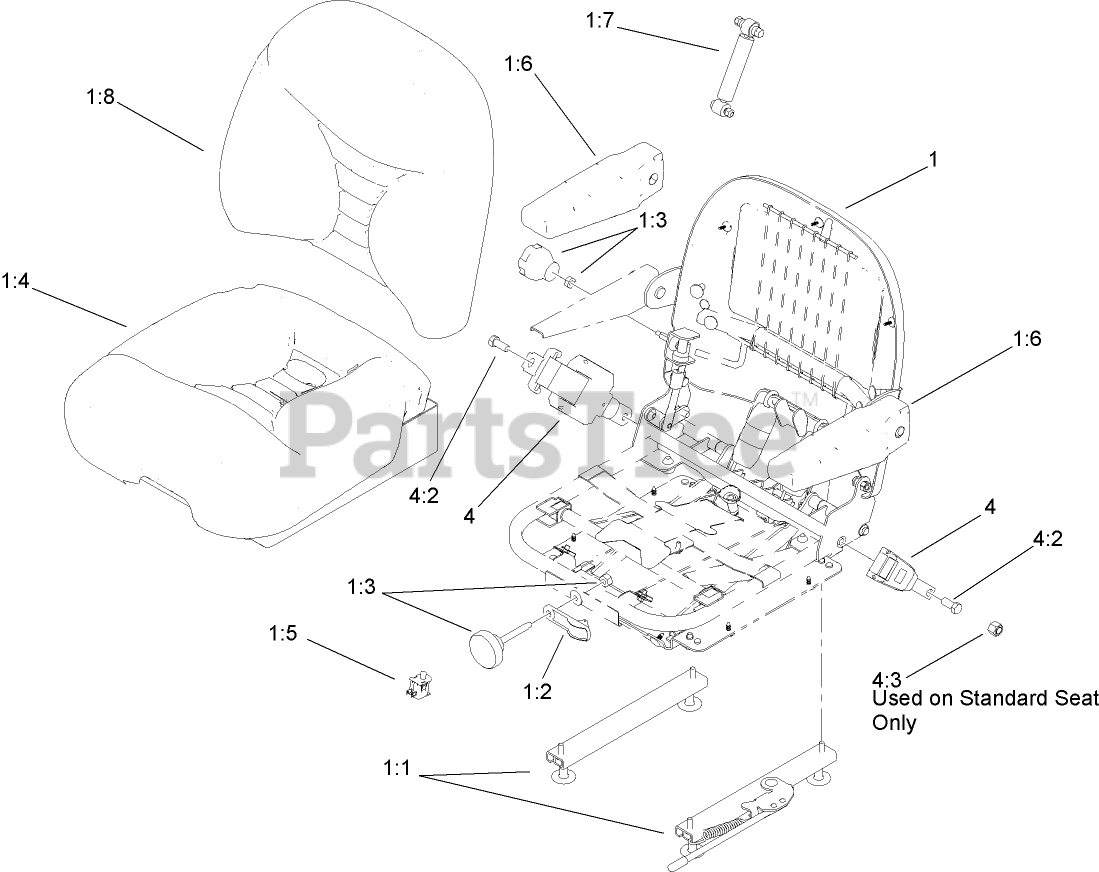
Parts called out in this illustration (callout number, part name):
1	SEAT ASM
1:1	Seat Track Kit
1:2	Weight Indicator Kit
1:3	Knob Kit
1:4	Bottom Cushion Kit
1:5	Switch Kit
1:6	PAD-ARMREST
1:7	Shock Absorber Kit
1:8	Back Cushion Kit
4	RETRACTABLE SEATBELT KIT
4:2	SCREW-HH
4:3	NUT-LOCK
